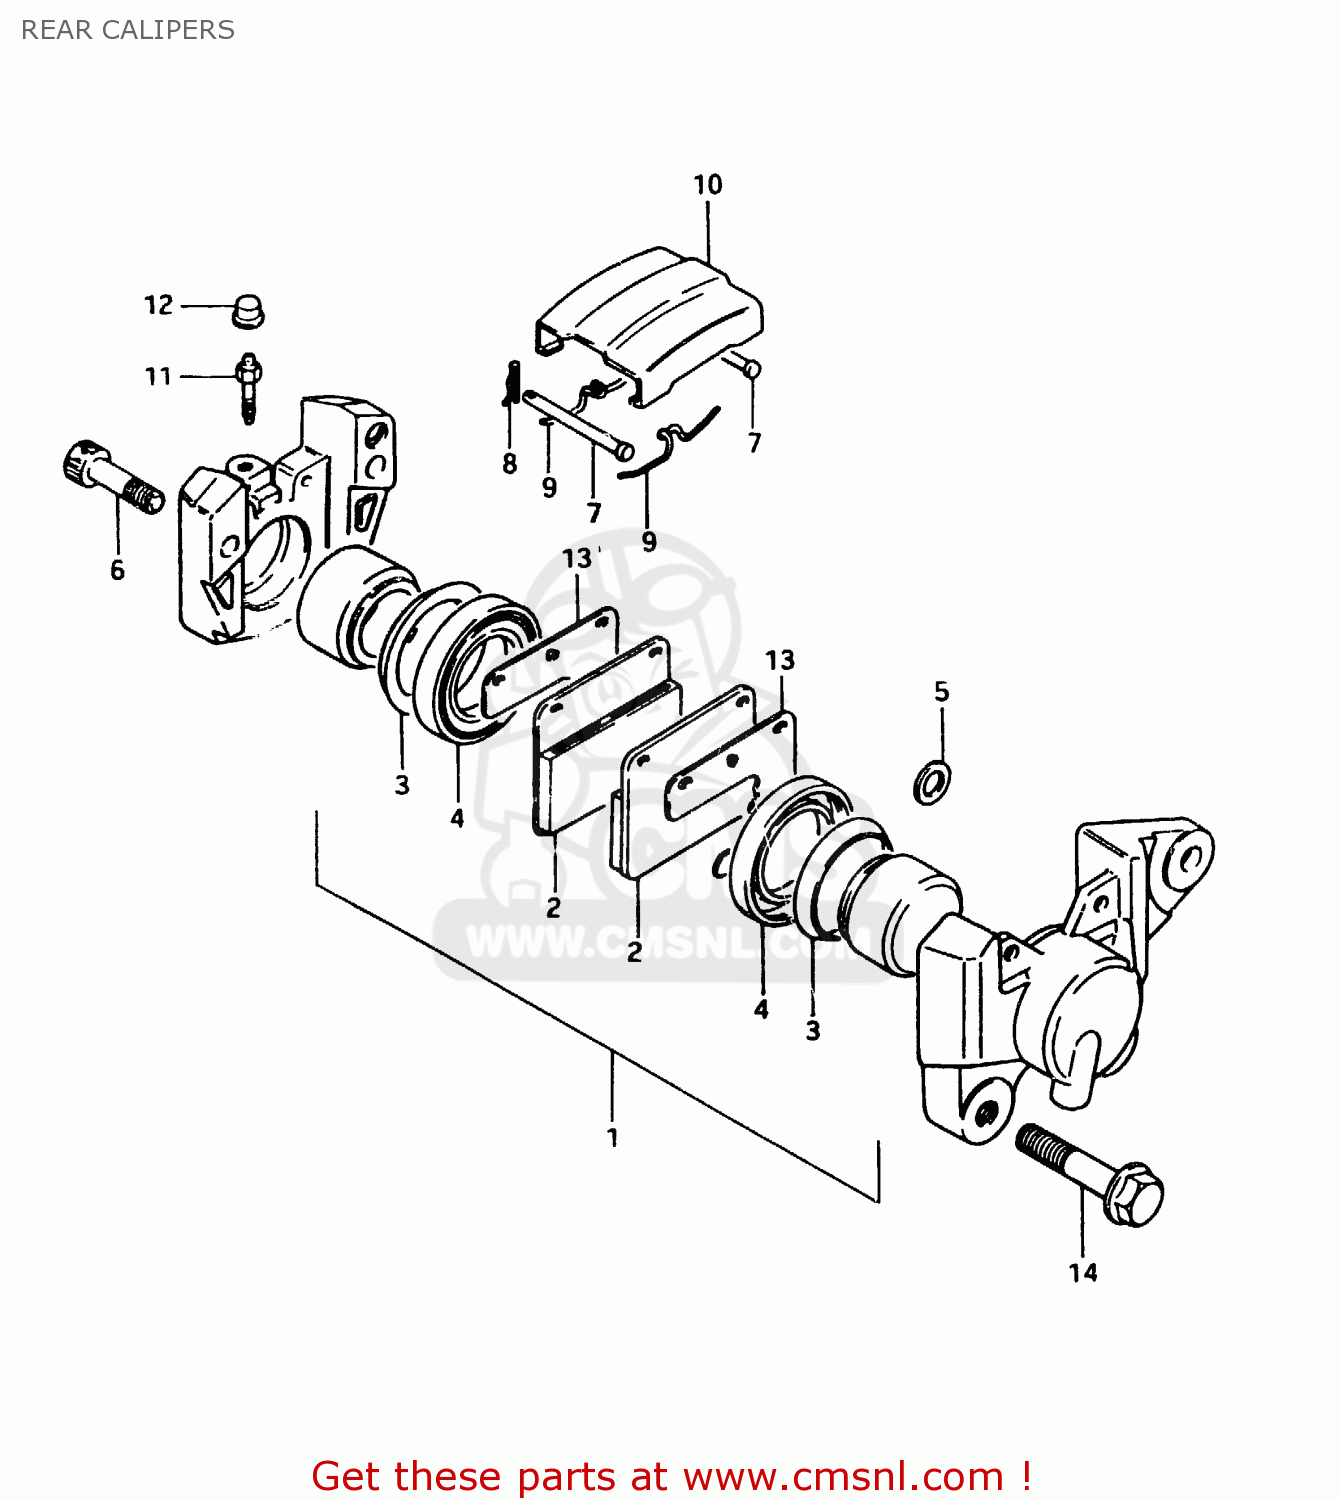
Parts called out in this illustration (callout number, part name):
1	PISTON SET
2	PAD,BRAKE (MCA)
3	SEAL,PISTON
4	BOOT,PISTON
5	SEAL,JOINT
6	BOLT,CALIPER HOUSING
7	PIN,PAD
8	CLIP,PAD PIN
9	SPRING
10	COVER,DUST
11	BLEEDER
12	CAP,BREATHER
13	SHIM,RR CALIPER
14	BOLT
